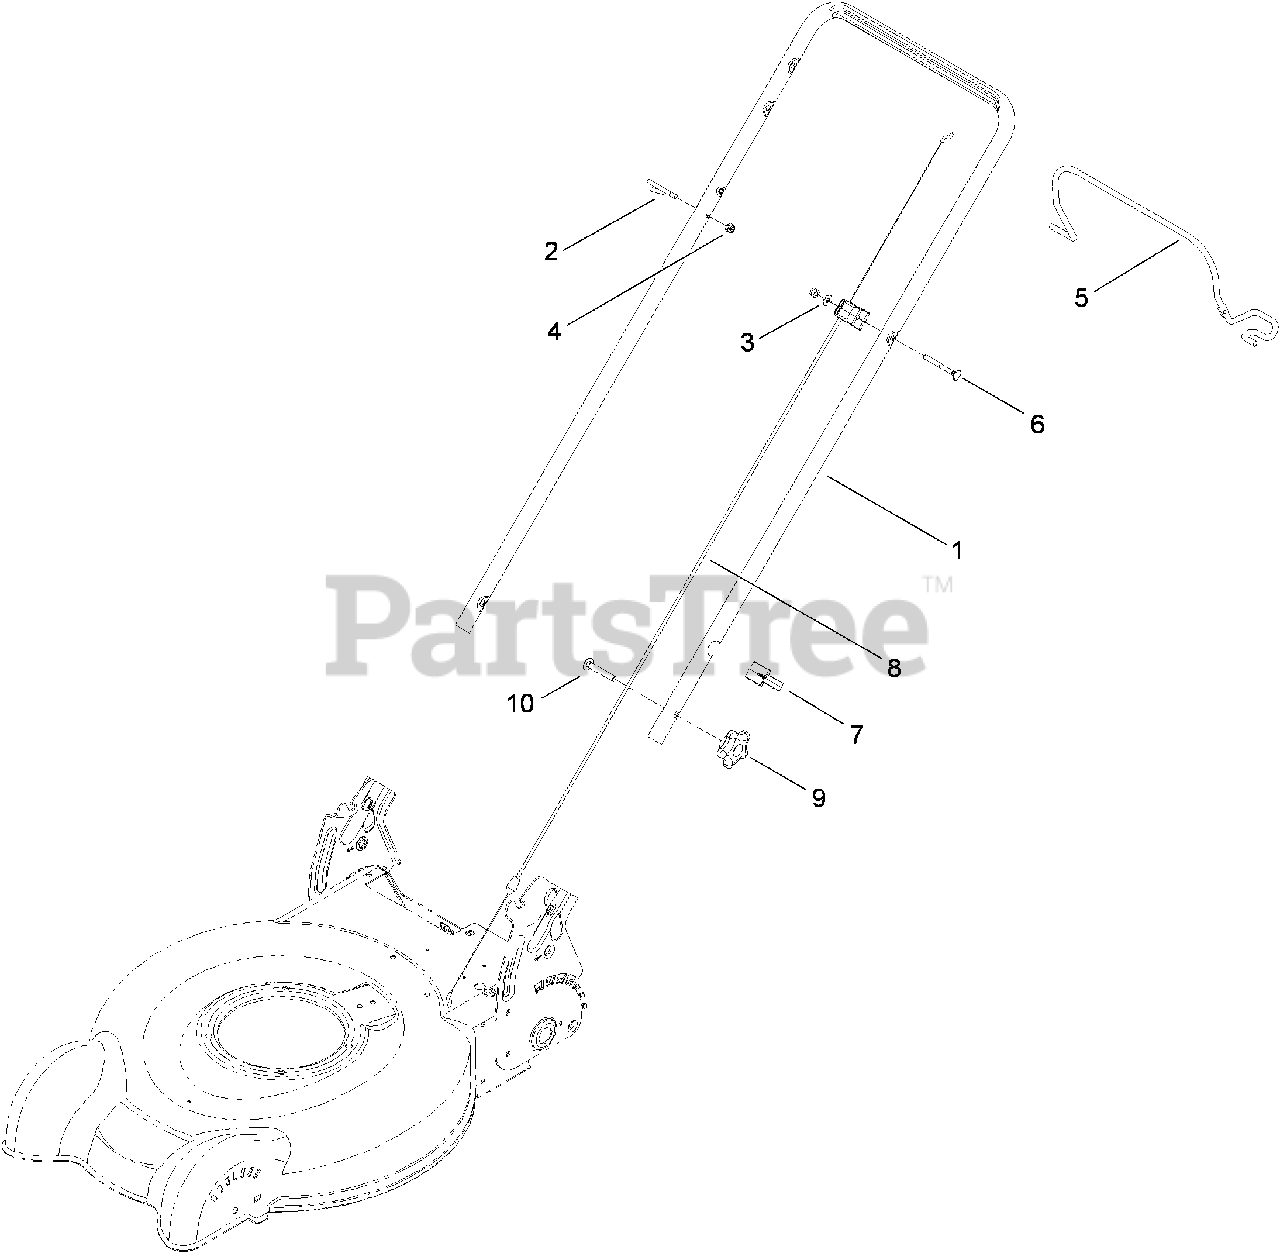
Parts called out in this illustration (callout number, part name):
1	HANDLE
2	GUIDE-ROPE
3	WASHER-FLAT
4	NUT-LOCK, NI
5	BAIL-BRAKE, LB
6	SCREW-HANDLE
7	GUIDE-CABLE
8	CABLE-BRAKE
9	KNOB-HANDLE, LOCKING
10	Screw-CARR
